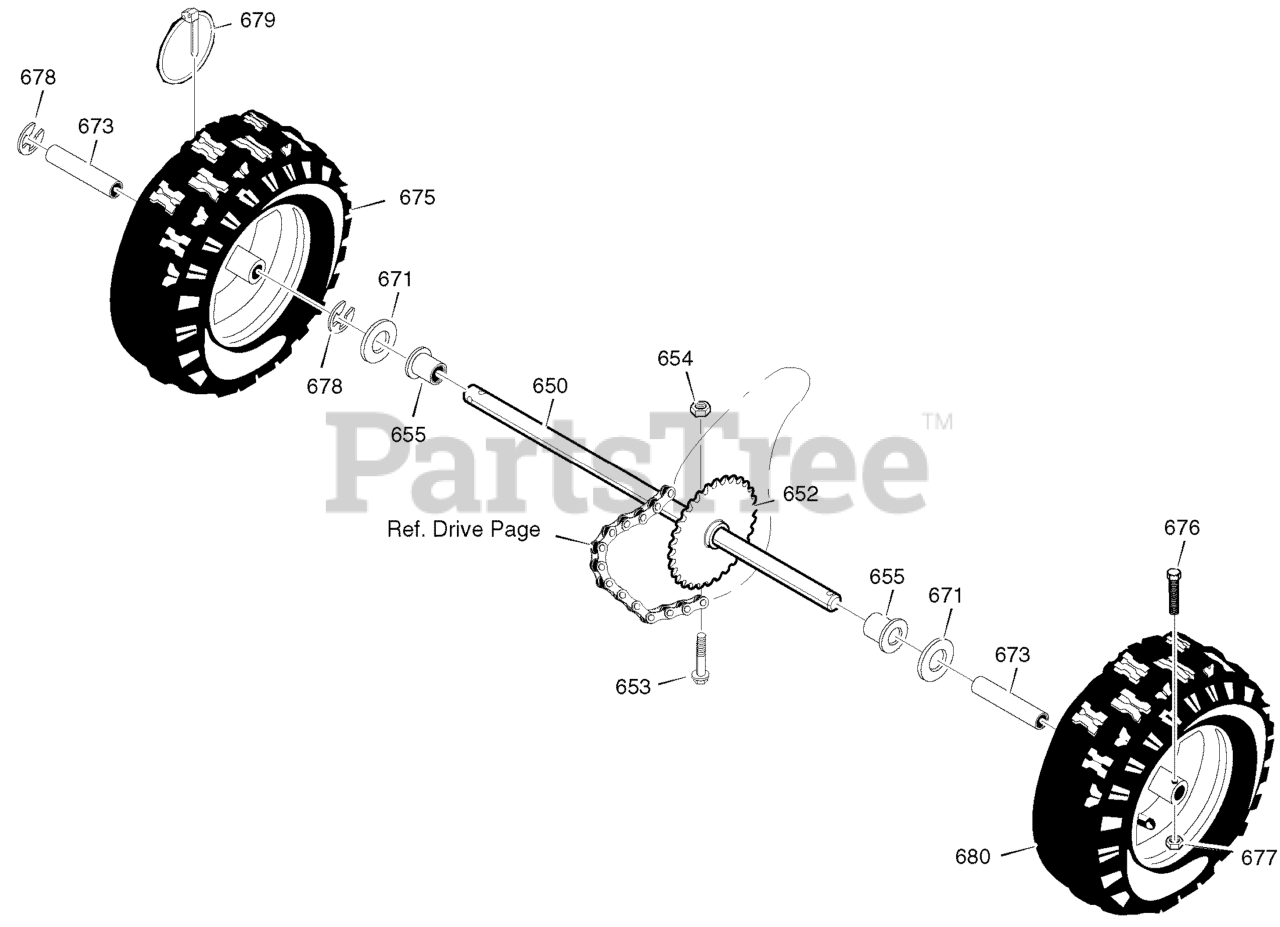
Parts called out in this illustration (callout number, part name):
650	SHAFT, AXLE
652	SPRKT & HUB
653	SCREW, 1/4-20 X 1.75
654	NUT, 1/4-20 HEX
655	BEARING, AXLE
671	WASHER, FLAT
673	BUSHING, WHEEL
675	TIRE & RIM, RIGHT
676	SCREW, 1/4-20X1.75 HH
677	NUT, 1/4-20 HEX
678	RING, RET
679	PIN, KLIK .25 X 1.38 DIA
680	TIRE & RIM, LEFT
